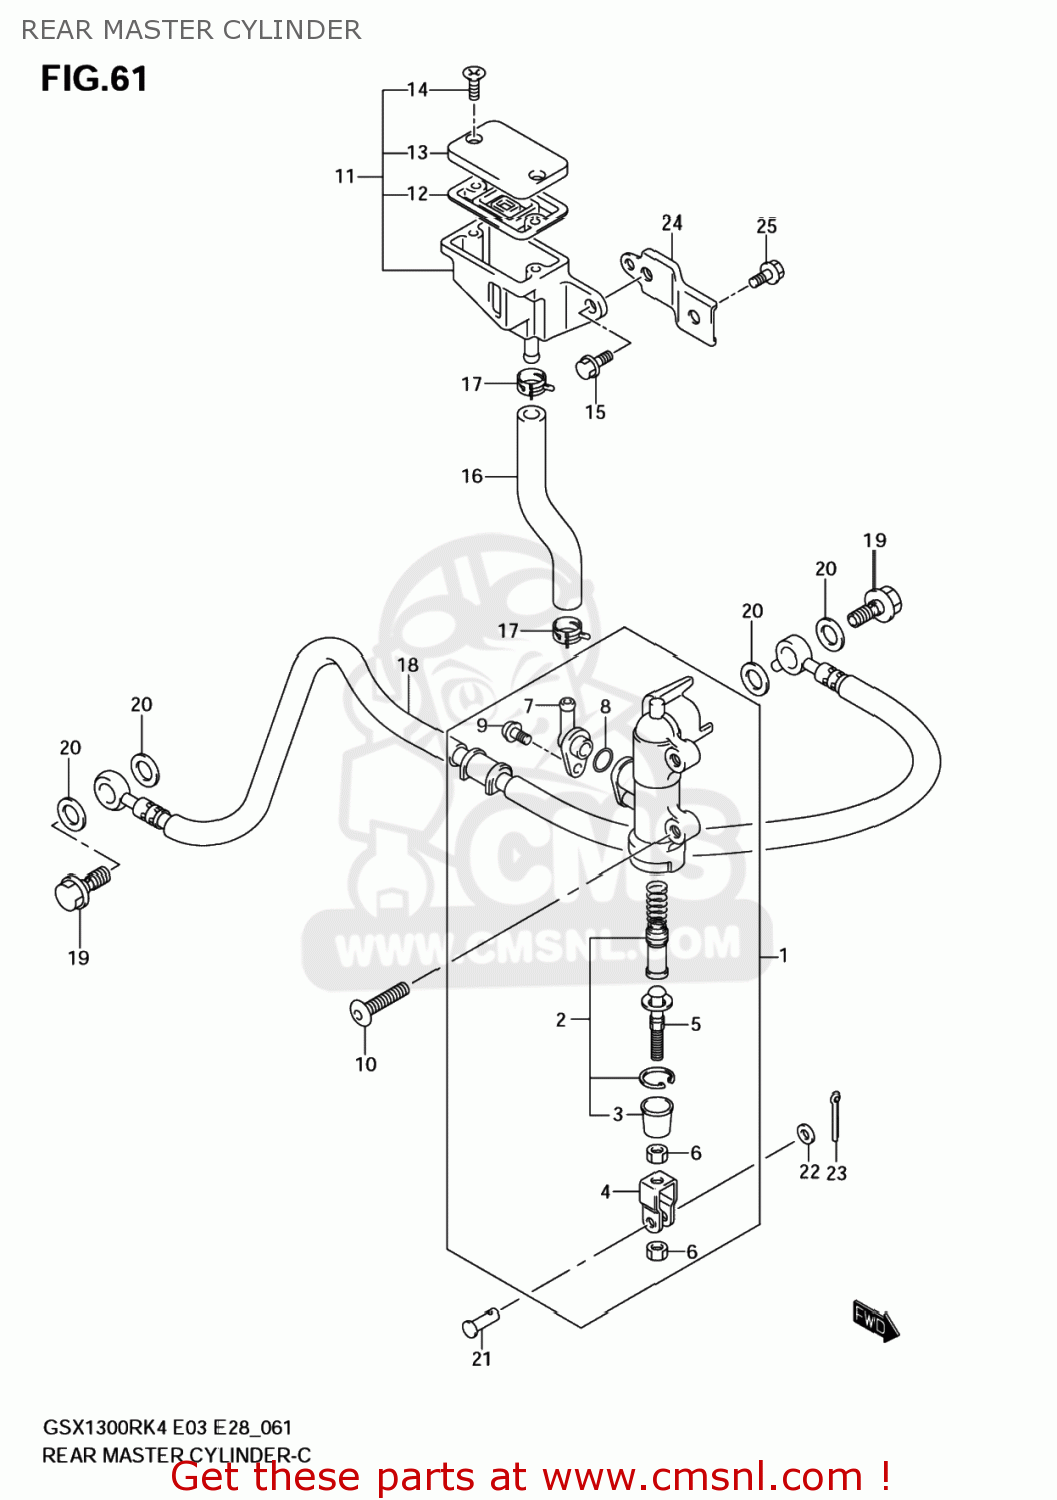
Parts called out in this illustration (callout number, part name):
1	CYLINDER ASSY,RR MASTER
2	PISTON/CUP SET
3	BOOT
4	YOKE
5	ROD,PUSH
6	NUT
7	CONNECTOR
8	O RING
9	SCREW
10	SCREW(6X20)
11	TANK ASSY,RR RESERVOIR
12	DIAPHRAGM
13	CAP
14	SCREW
15	BOLT
16	HOSE,RESERVOIR TANK
17	CLIP
18	HOSE,REAR BRAKE
19	BOLT UNION
20	WASHER(10X15X1.5)
21	PIN
22	WASHER
23	PIN
24	BRACKET,RR RESERVOIR TANK
25	BOLT
